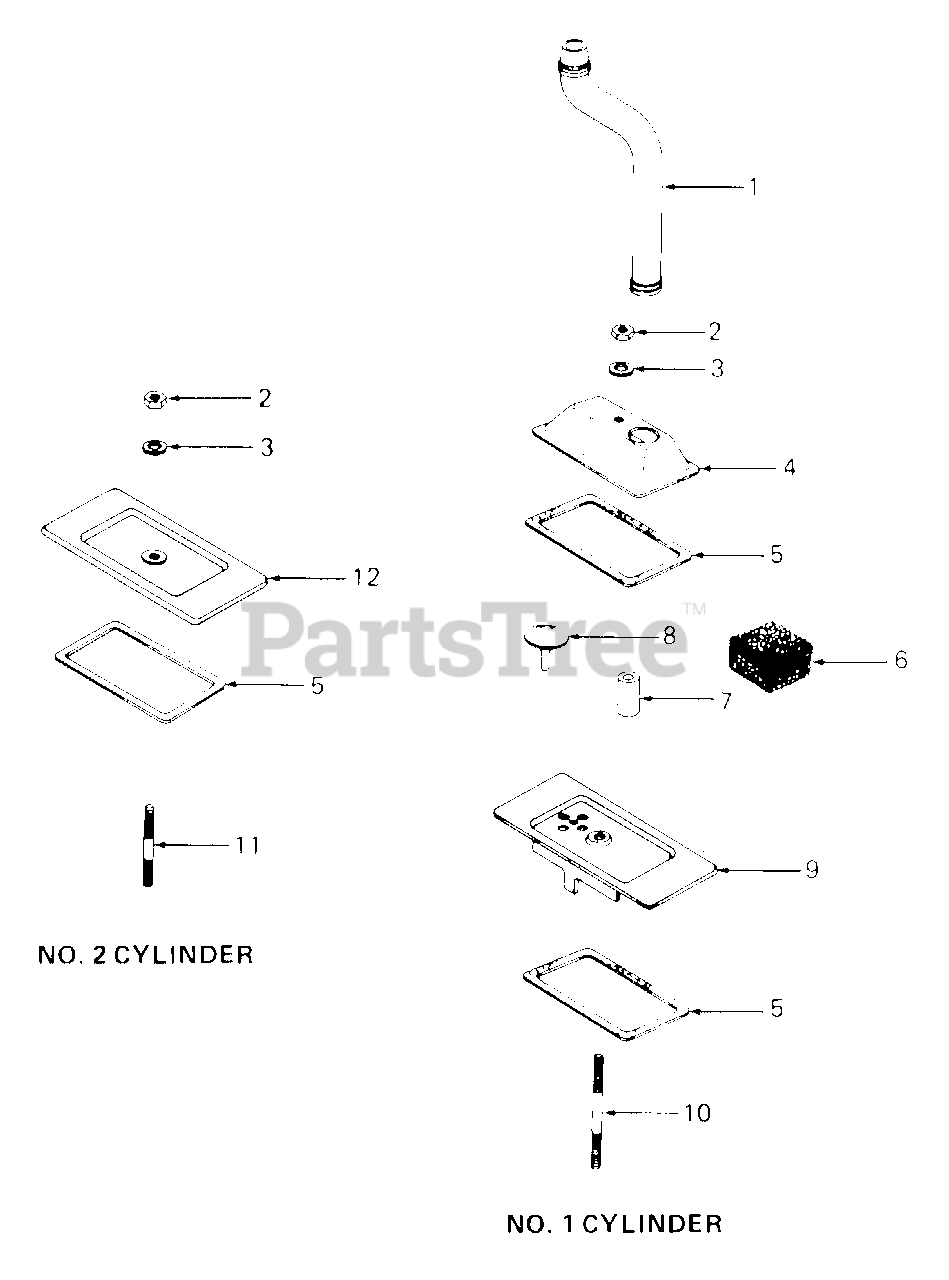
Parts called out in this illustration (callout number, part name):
1	Hose, Breather
2	Nut, Hex, 1/4-20
3	Washer, Plain, 1/4
4	Cover, #1 Upper Cylinder Valve
5	Gasket, Valve Cover
6	Filter, Breather
7	Seal, Breather
8	Valve, Breather
9	Cover, #1 Lower Cylinder Valve
10	Stud, #1 Cylinder Valve Cover, 1/4-20 X 3.25 Lg
11	Stud, #2 Cylinder Valve Cover, 1/4-20 X 2.25 Lg
12	Cover, #2 Cylinder Valve
